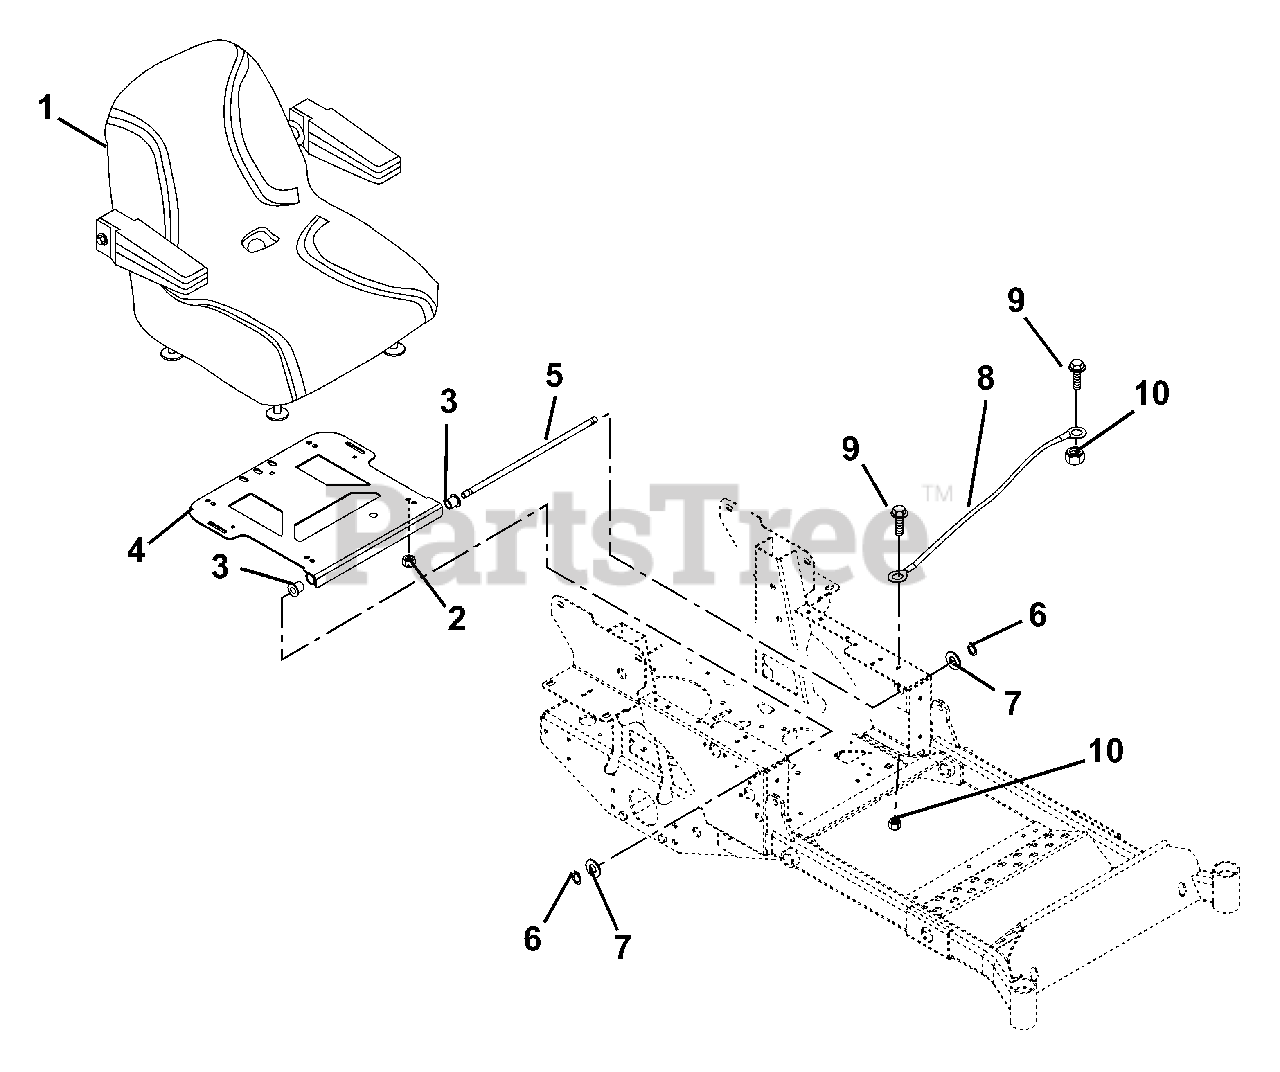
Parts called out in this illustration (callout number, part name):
2	Nut, Nyloc Flange 5/16-18
3	Bushing, Flange .515 x .750 x .745 x 1.00
4	Seat Pivot Mount
5	Rod, Seat Frame Pivot
6	Ring, Retaining External .50 x .05
7	Washer, Flat Steel .531 x 1.06 x .095
8	Cable, Hood
9	Bolt, Hex .25-20 x .75 Grade 5
10	Nut, Nyloc Flange .25-20
11	Knob,
